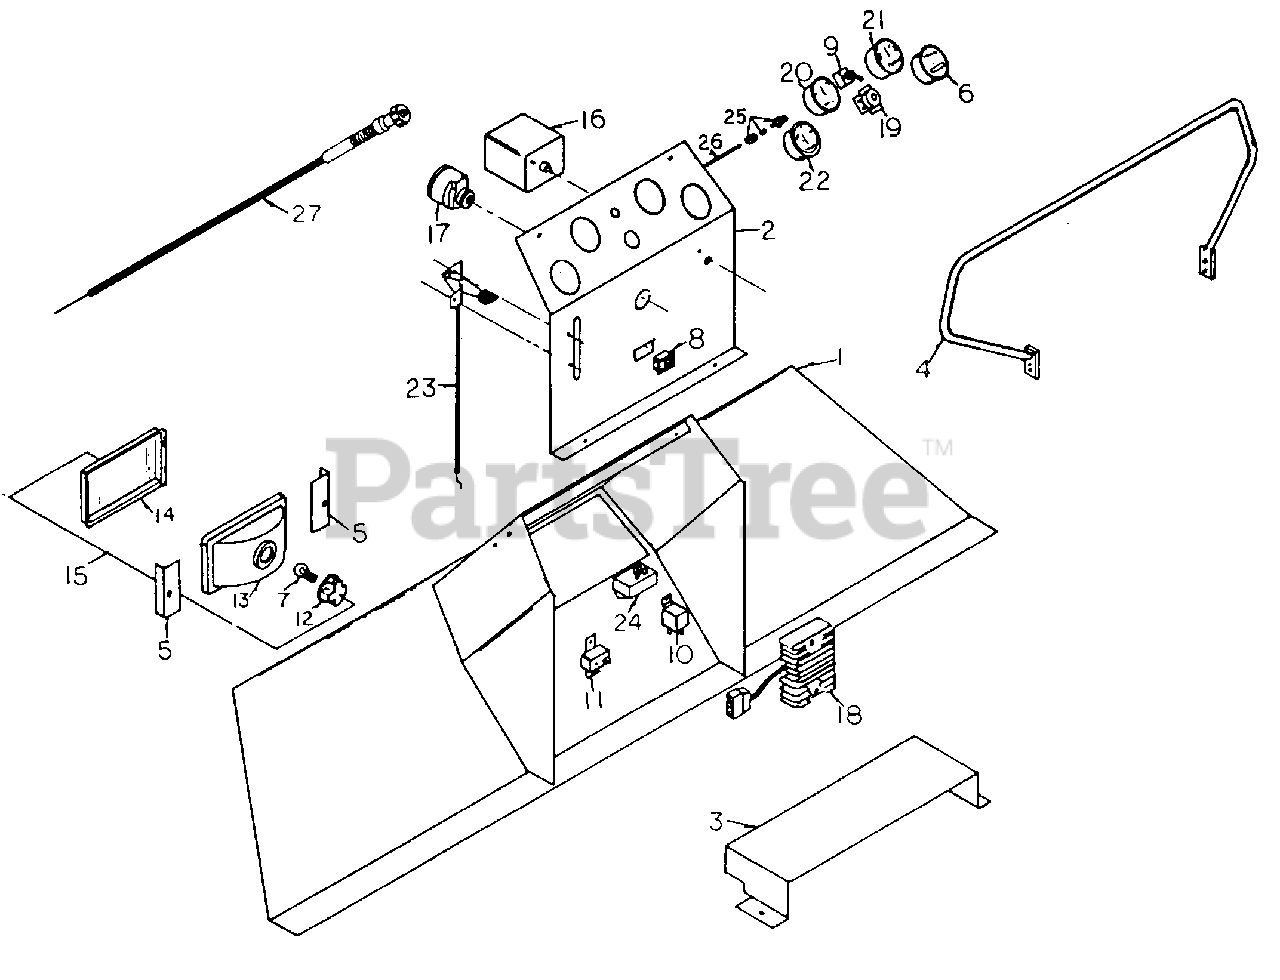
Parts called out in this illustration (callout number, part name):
1	Console Housing
2	Dash
3	Tunnel
7	Light Bulbs
8	Light Switch
9	PTO Switch
10	Electrlc Clutch Relay
11	40 Amp Clrcuit Breaker
13	Lamp
14	Lens
15	Light Assembly
17	lgnition Switch
18	Rectifler Regulator, 3Cylinder Only
19	Glow Plug Indicator, Diesel Only
20	Oil Gauge
21	Temperature Cauge
23	Throttle Cable, Diesel
25	Compresslon Fltting
27	Throttle Cable, Gas
